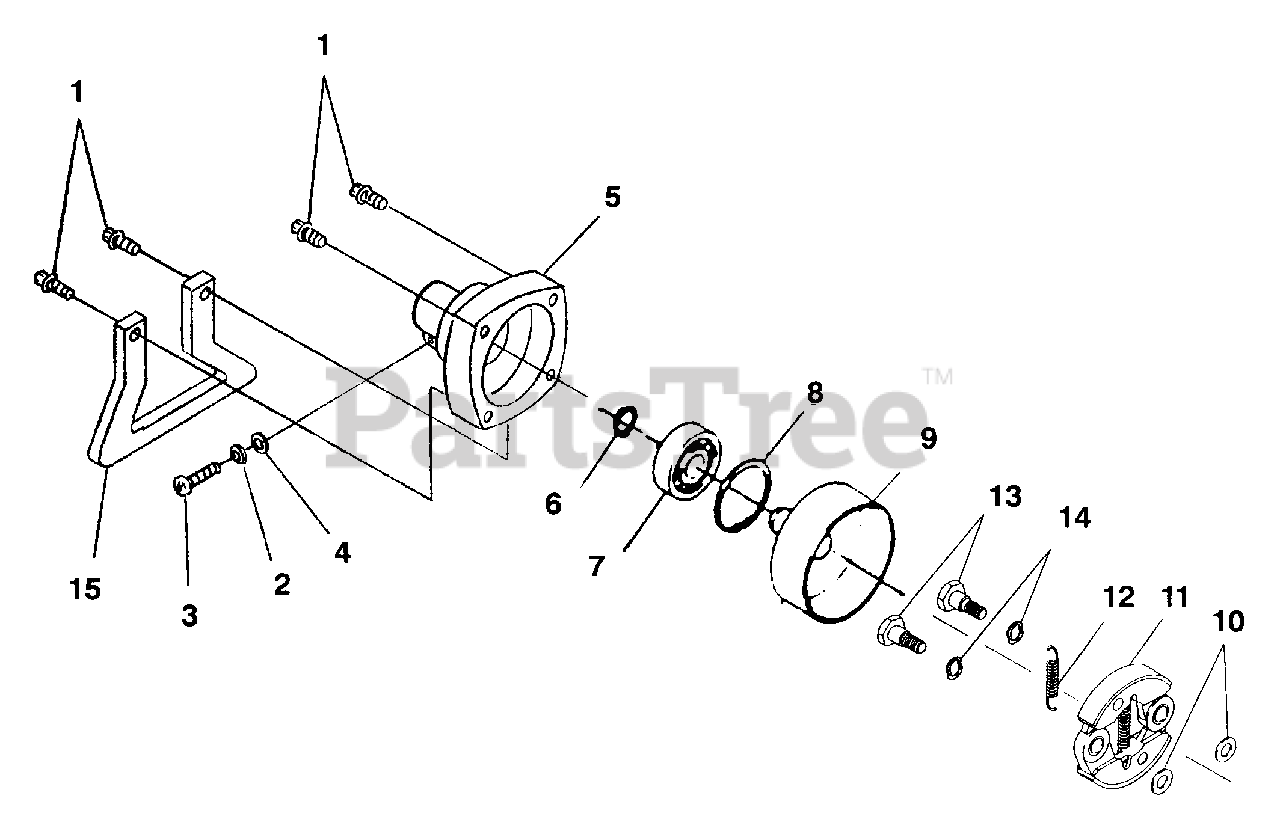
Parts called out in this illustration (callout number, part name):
1	Bolt & Washer
3	Screw
5	Clutch Case
6	Snap Ring
8	Snap Ring
9	Clutch Drum
11	Clutch Shoe Kit
12	Clutch Spring
13	Bolt
15	Stand
